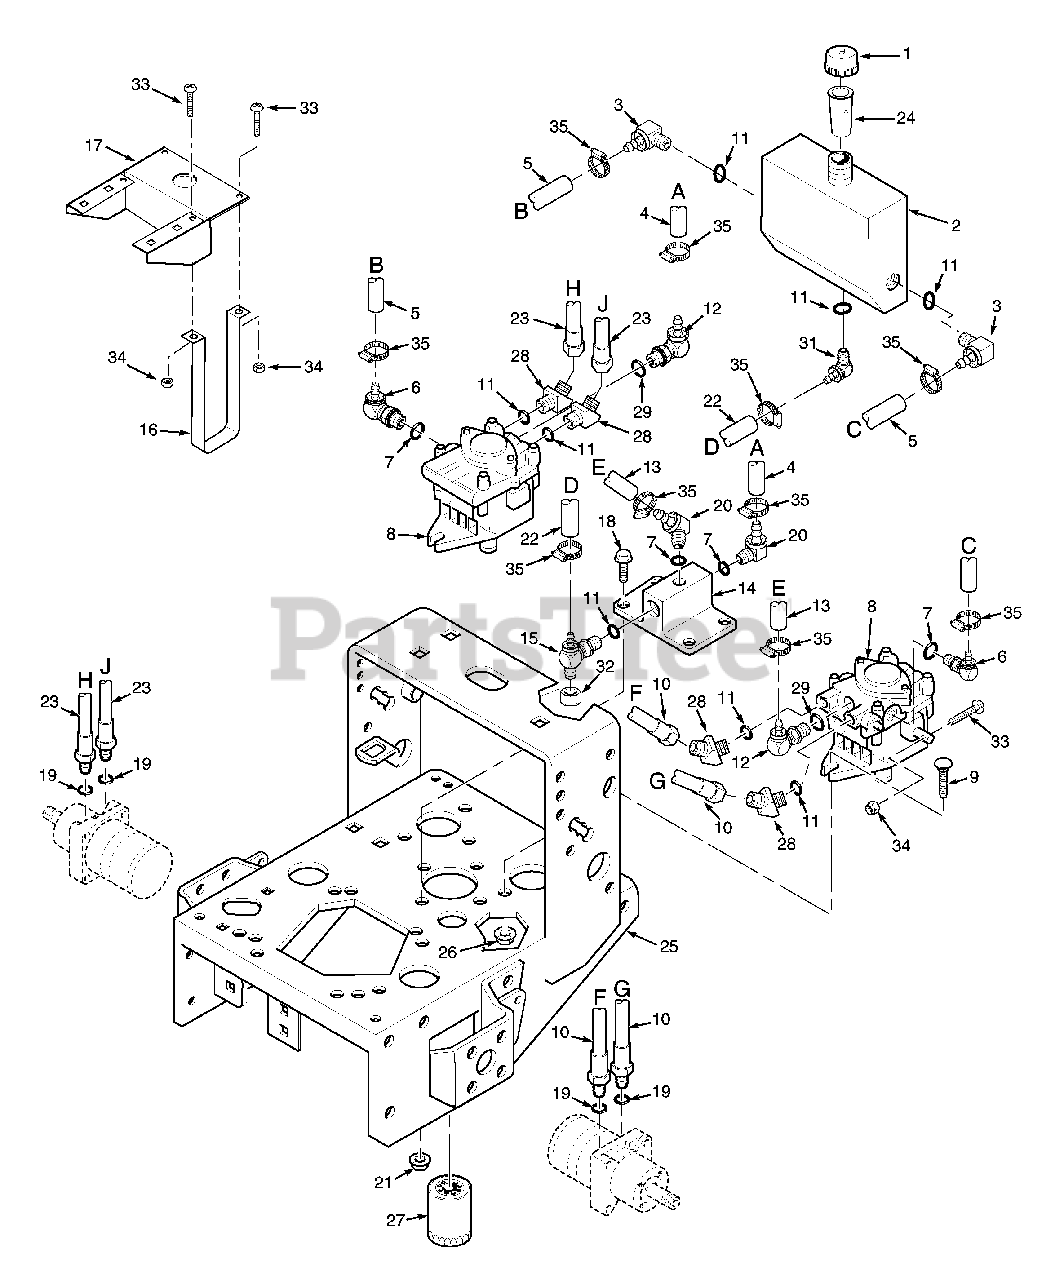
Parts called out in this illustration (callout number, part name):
1	Cap, Oil Reservoir
2	Oil Reservoir (With Fittings)
3	Elbow, 9/16 O-Ring x 3/8 Hose
4	Hose, 3/8" ID - 16" Long (Order By The Inch)
5	Hose, 3/8" ID - 7" Long (Order By The Inch)
6	Elbow, 90 deg. 7/16-20 JIC to 9/16-18 "O" Ring
7	O-Ring
8	Pump, Hydro-Gear BDP-10L117
9	Bolt, Carriage, 3/8-16 x 1.25"
10	Hose, Pump to Wheel Motor
11	O-Ring
12	Elbow, 7/16 O-Ring x 3/8 Hose
13	Hose, 3/8" ID - 10-1/4" Long (Order By The Inch)
14	Oil Filter Base
15	Tee, 3/8 O-Ring x JIC x 1/2 Hose
16	Strap, Hydraulic Tank
17	Bracket, Hydraulic Tank
18	Capscrew, 5/16-18 x .75" Serr. Flange
19	O-Ring
20	Elbow, 9/16 O-Ring x 3/8 Hose
21	Nut, 5/16-18 Serr. Flange
22	Hose, Formed 1/2" ID
23	Hose, Pump to Wheel Motor
24	Tube, Filler Neck
25	Engine Deck (16" Wide) W/Decals - Small Frame
26	Nut, 3/8-16 Serr. Flange
27	Oil Filter
28	Elbow, 45 Deg.-3/4-16 JIC Male x Male 3/4-16 O-Ring
29	O-Ring
30	Coupling, 3/8 Pipe to 1/2 Push-on
31	Elbow, 3/4-16 O-Ring x 1/2 Hose
32	Cap, 3/4-16
33	Screw, 1/4-20 x 2.0" Round Head Phillips
34	Nut, 1/4-20
35	Clamp, .87 max dia.
